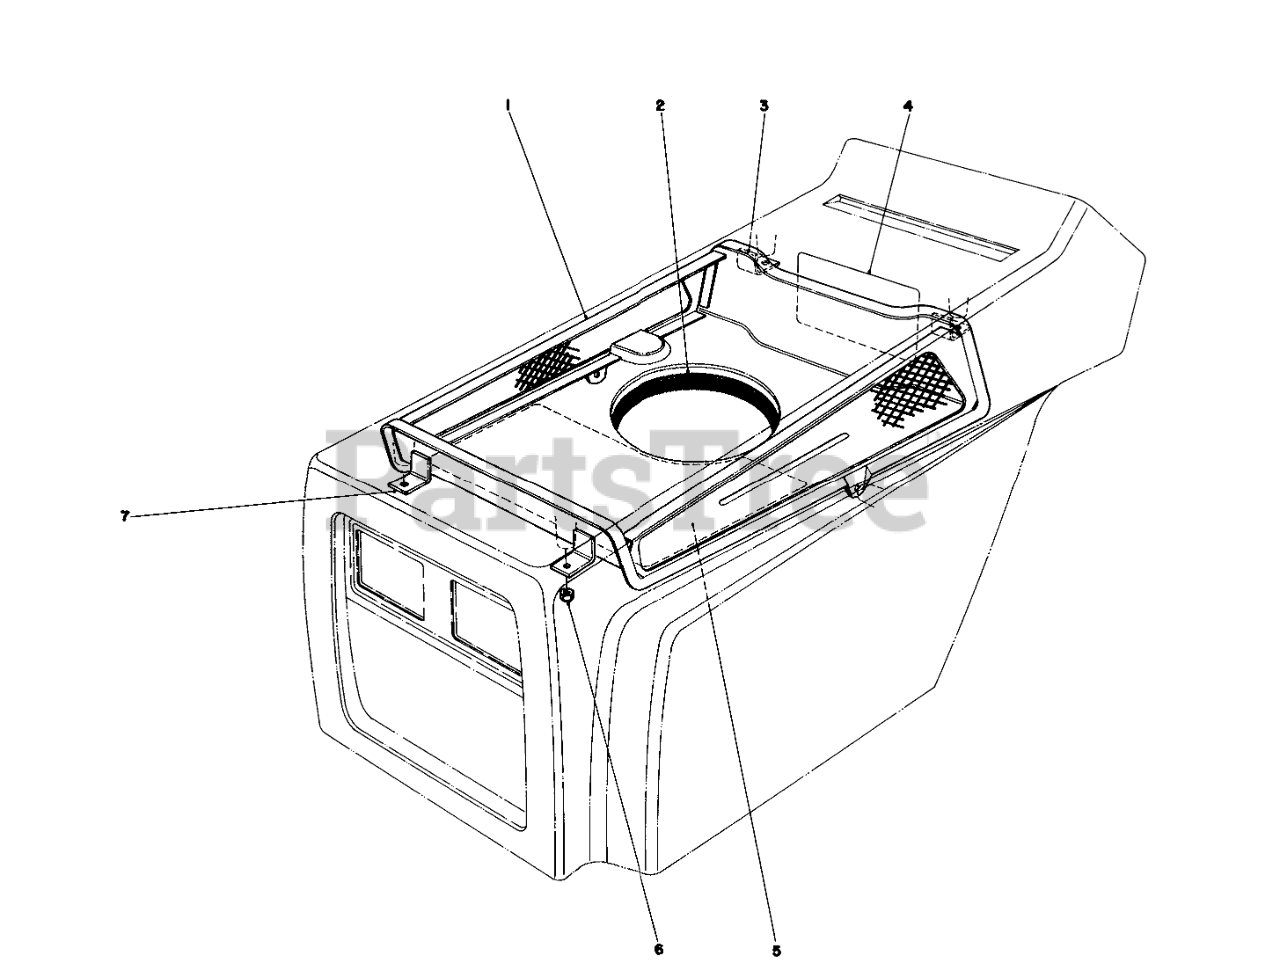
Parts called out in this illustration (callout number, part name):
1	Duct Hood
2	Seal Engine
3	Bracket Rear Duct Support
4	Decal-Belt Change
5	Decal Service
6	NUT-LOCK, CONE
7	Bracket Duct Support
